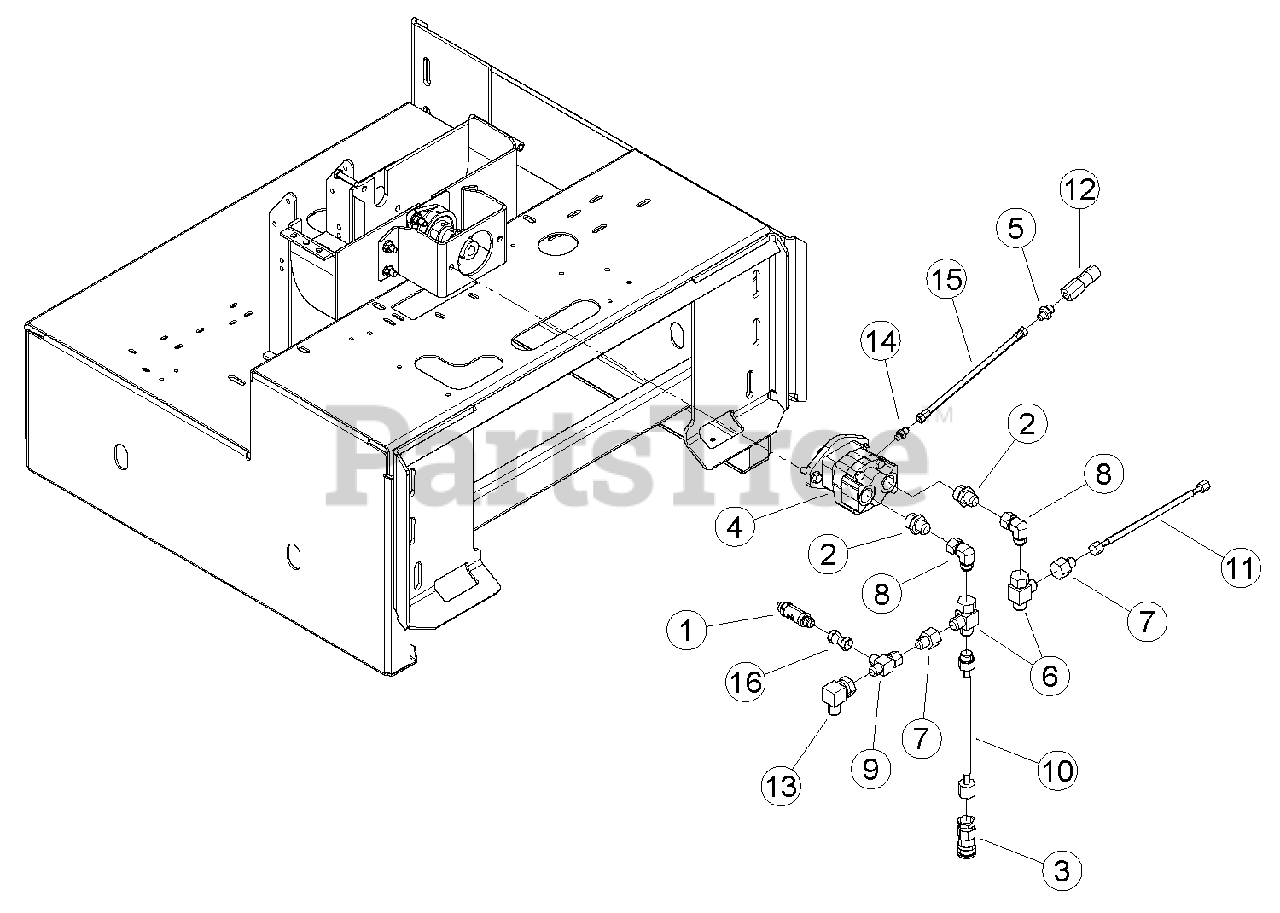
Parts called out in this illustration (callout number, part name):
1	VALVE, -10 MJIC / -10 MJIC CHECK
2	ADAPTER, -16 MORING / -12 MJIC
3	COUPLER, FEMALE QUICKTACH
4	MOTOR, 1.24 CU. IN. HYD
5	ADAPTER, -8 MORING / -6 MJIC
6	ADAPTER, -12 FMJIC / -12 MJIC / -12 MJIC
7	ADAPTER, -12 FMJIC / -10 MJIC
8	ADAPTER, -12 FMJIC / -12 MJIC 90 DEG.
9	ADAPTER, -10 FMJIC / -10 MJIC / -10 MJIC
10	HOSE, 1 X 114 -12 FMJIC / -12 MORINGSW
11	HOSE ASSY, -10 FMJIC / -10 FMJICSW X 16
12	COUPLER, FEMALE FLATFACE -8
13	ADAPTER, -10 FMJIC / -10 MJIC 90 DEG.
14	ADAPTER, -4 MORING / -6 MJIC
15	HOSE, .250 X 102 -6 FJICSW / -6 FJICSW
16	ADAPTER, -10 FJIC / -10 FJIC SRT SWIVEL
